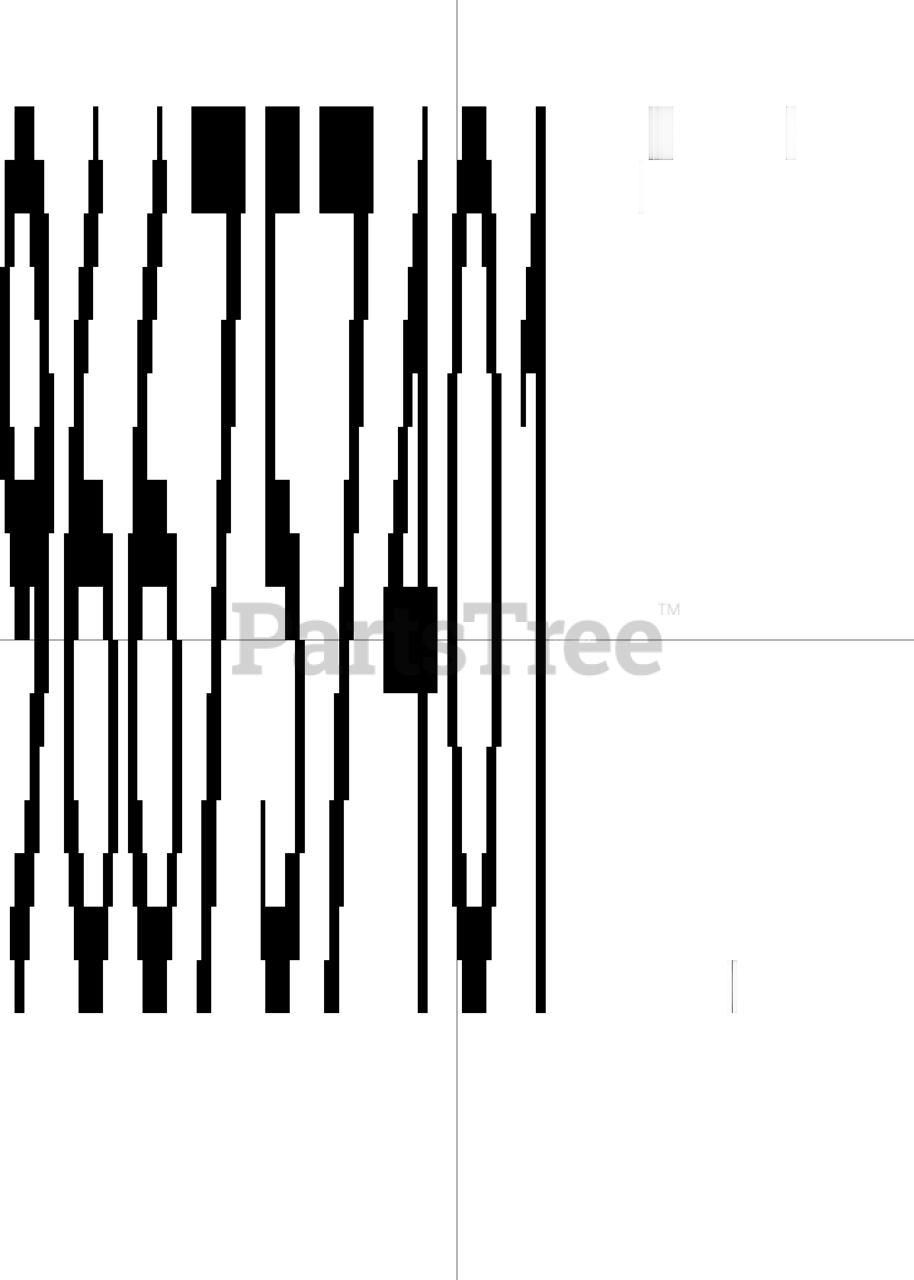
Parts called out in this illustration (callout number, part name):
2	SPRING BRACKET
5	STEERING WHEEL
7	NUT
8	STEERING ROD
9	SPACER
13	BALL BEARING 6004-2RS1
17	CIRCLIP SGH 47
20	COLLAR SCREW
22	WIRE ASSY
25	RETAINING RING
26	STEERING CHAIN
28	WIRE GUIDE
29	NUT
31	Ball Bearing 6005-2rs
32	BALL BEARING 6010 2RS1
33	CIRCLIP SGH 47
34	RETAINING RING SGA 25
40	NUT
41	COLLAR SCREW
42	PROTECTIVE COVER
43	NUT
